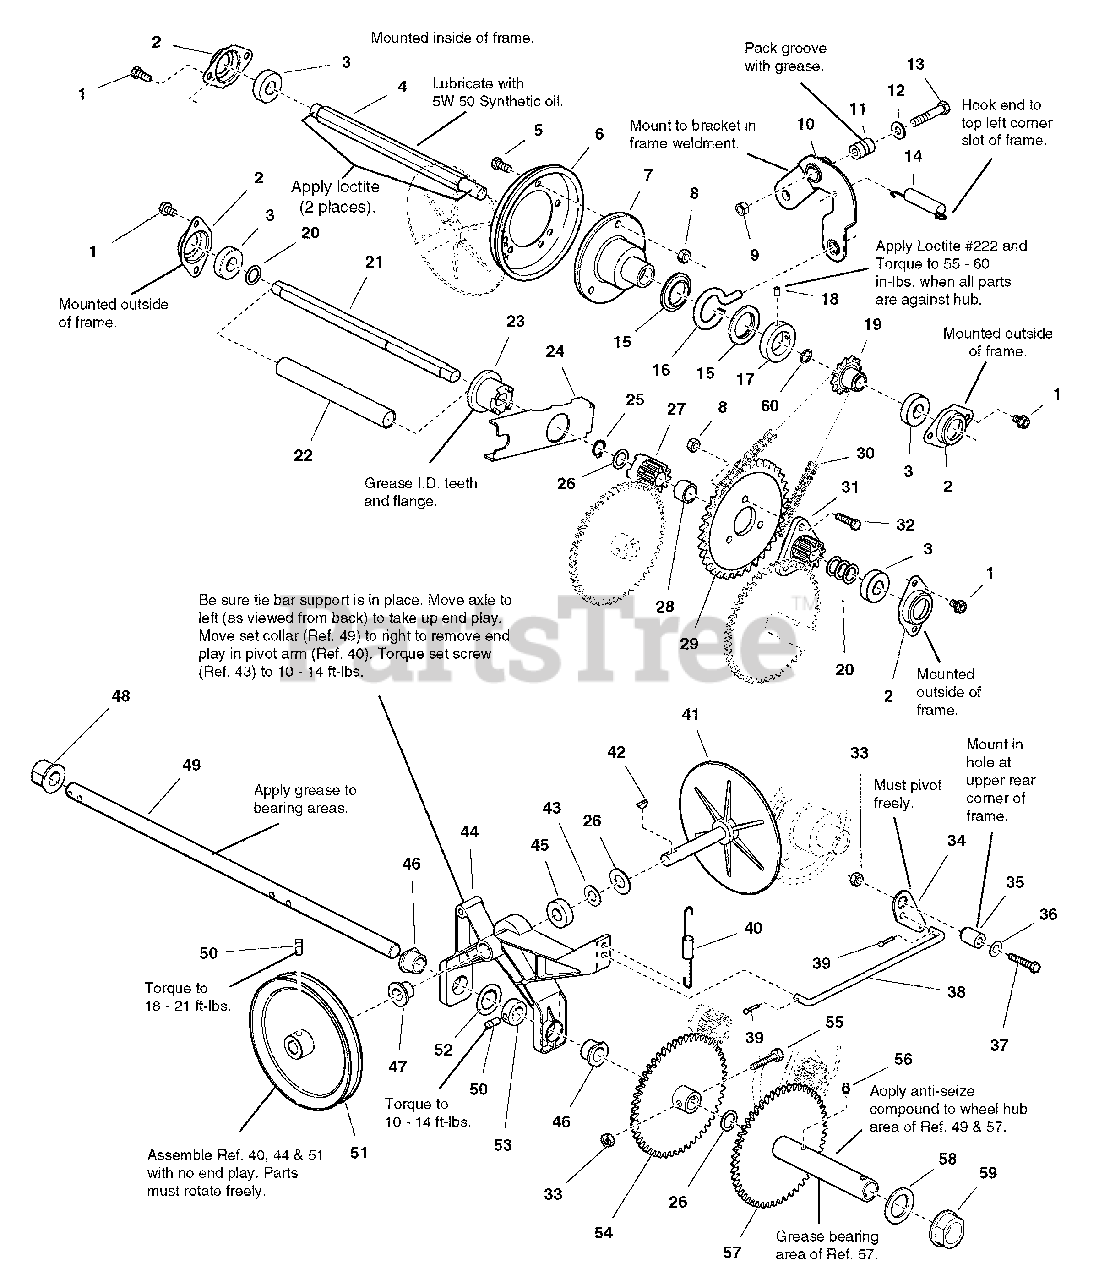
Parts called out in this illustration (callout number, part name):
1	SCREW, Hex Washer Head Taptite, 5/16-18 x 5/8
2	RETAINER, Bearing
3	BEARING, Ball
4	SHAFT, Hex
5	CAPSCREW, Hex Head, 5/16-18 x 3/4, G5
6	DISC, Friction with Insert
7	HUB, Friction Disc
8	NUT, Hex Keps Conical Washer, 5/16-18
9	NUT, Hex Flange, 3/8-16 ESNA
10	ARM ASSEMBLY, Shift with Bushing
11	BUSHING, 19/50 ID x 3/4 OD x 1-3/100 LG
12	WASHER, 3/8
13	CAPSCREW, Hex Head, 3/8-16 x 2, G5
14	SPRING, Extension
15	COLLAR, Thrust
16	PIN, Loop
17	COLLAR, Set
18	SCREW, Set Square Head Cup Point, 1/4-20 x 1/2
19	SPROCKET, 10 T
20	WASHER, 5/8
21	JACKSHAFT, Double D
22	SPRING, Complete
23	CLUTCH, Sliding, 1/5 LG, Powdered Metal
24	ARM, Clutch
25	RING, Retaining Extension
26	WASHER, 3/4
27	GEAR, Stationary Clutch
28	SPACER, Heat Treated, 31/100 LG
29	SPROCKET
30	CHAIN, Roller
31	GEAR, Double D
32	CAPSCREW, Hex Head, 5/16-18 x 1, G5
33	NUT, Hex Flange, 5/16-18 ESNA
34	BELLCRANK
35	BUSHING, 11/32 ID x 3/4 OD x 1-3/50 LG
36	WASHER, 11/32 x 3/4 x 1/16
37	CAPSCREW, Hex Head, 5/16-18 x 1-3/4, G5
38	ROD, Pivot, 9-15/100 LG
39	PIN, Quick
40	SPRING, Extension
41	DRIVE DISC with SPINDLE
42	KEY, Woodruff, 47/250 x 5/8
43	WASHER, 5/8
44	ARM, Pivot with Bushings & Bearings
45	BEARING, Ball
46	BUSHING, 3/4 ID x 1 OD x 3/4 LG, Powdered Metal
47	BUSHING, 5/8 ID x 13/16 OD x 3/4 LG, Powdered Metal
48	BUSHING, 377/100 ID x 1-13/100 OD x 1 LG, Powdered Metal
49	AXLE, Round
50	SCREW, Set Square Head Cup Point, 5/16-18 x 1/2 G8
51	PULLEY & HUB ASSEMBLY
52	WASHER
53	COLLAR, Set
54	GEAR & HUB ASSEMBLY, R.H.
55	CAPSCREW, Hex Head, 5/16-18 x 1-1/2, G8
56	FITTING, Lube, 1/4-28, Tappered with Check Ball
57	GEAR & HUB ASSEMBLY, with Bushings
58	WASHER, 1-47/250
59	BUSHING, 1-27/200 ID x 1-157/250 OD x 3/4 LG
60	RING, Retaining External, #87
